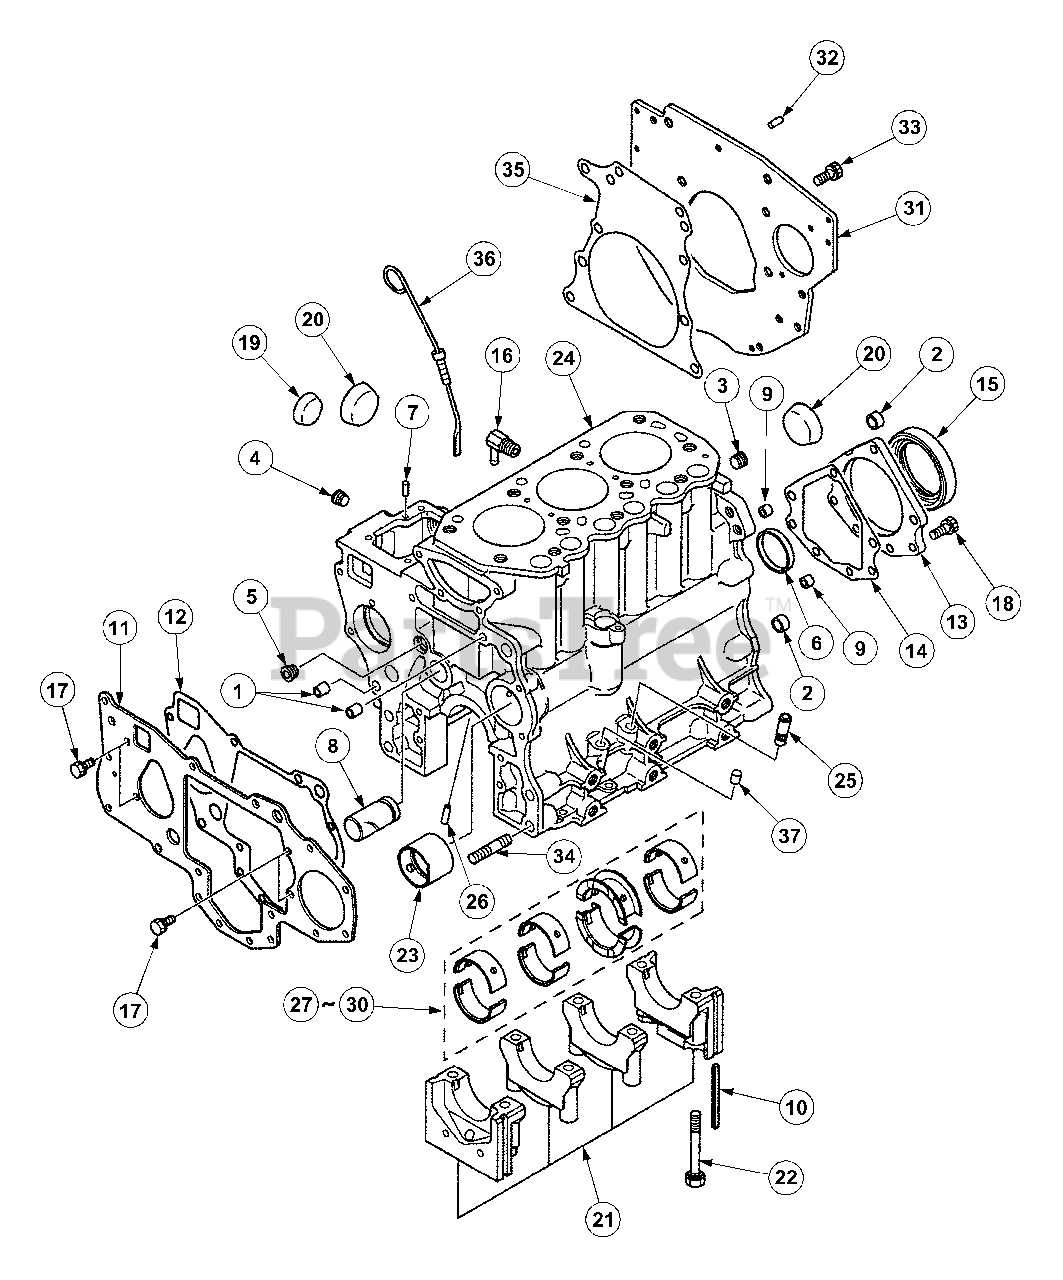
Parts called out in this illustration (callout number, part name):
1	Bushing,Knock
2	Bushing,Knock
8	Shaft,Idler
9	Bushing,Knock
13	Case,Oil Seal
14	Gasket,Oil Seal
16	Joint,Water Drain
17	Bolt,w/Washer
18	Bolt,w/Washer
19	Cap,Sealing
20	Cap,Sealing
21	Cap Assy
22	Bolt,Bearing
23	Bushing,Cam
24	Block,Cylinder
25	Guide,Oil Level
27	Bearing Set
33	Bolt,w/Washer
36	Gage,Oil Level
